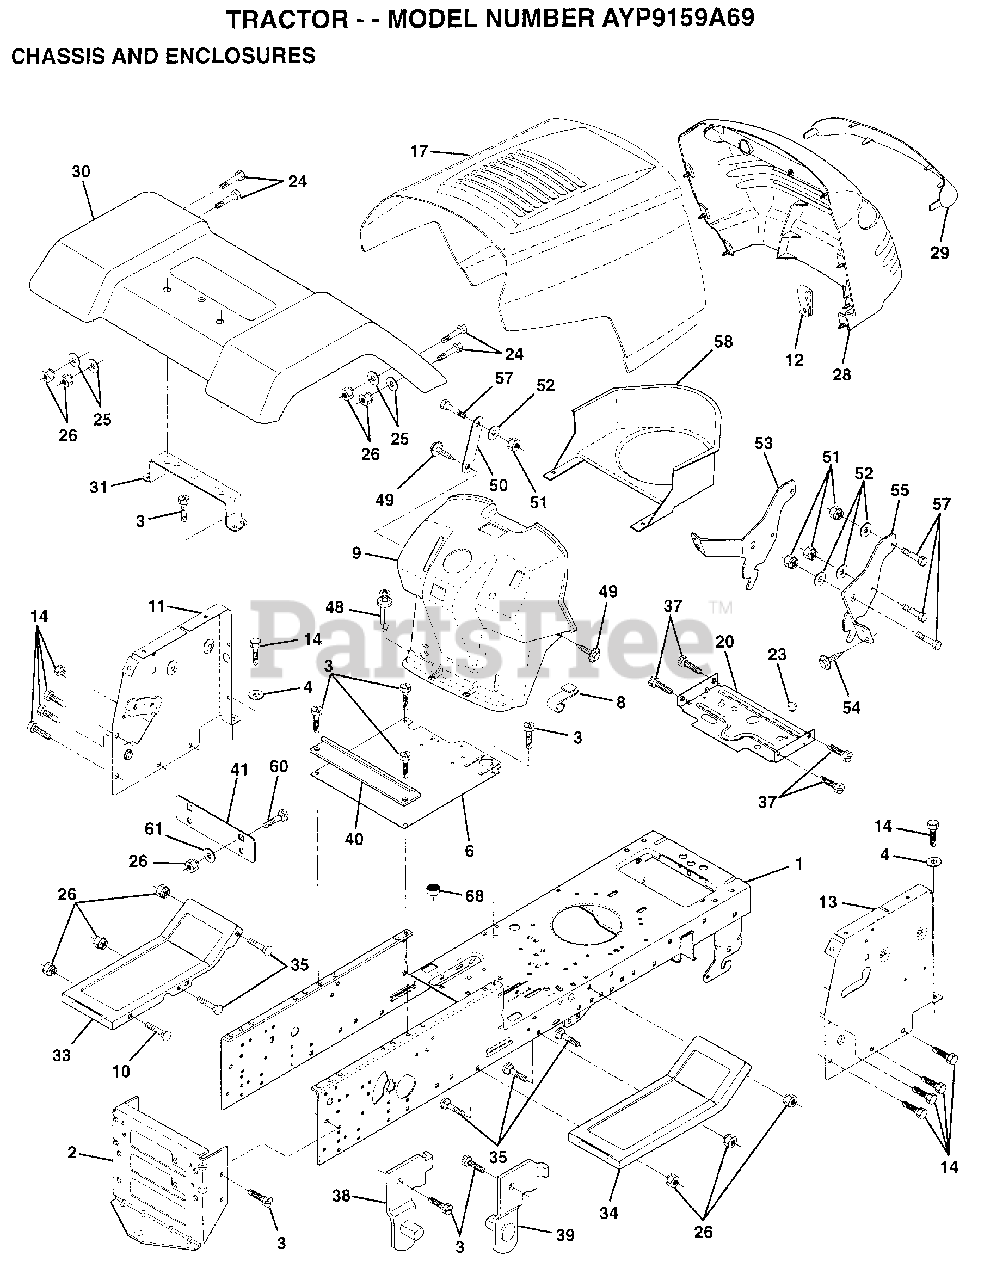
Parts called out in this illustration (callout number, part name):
1	CHASSIS.WLD.11GA
3	SCREW
4	WASHER
8	"CLIP,INSULATOR"
11	PANEL.DASH.LH.A
12	CLIP.TINNERMAN
13	PANEL.DASH.RH.
14	SCREW LT
17	HOOD.STL.PRV.LB
20	PLATE.MTG.BTRY.TK
24	BOLT
25	WASHER
26	NUT
28	GRILL.P/L.EURO.
29	LENS.EURO.W/DECAL
30	FENDER.PNT.LT.
31	BRACKET SUPT FEND
33	FOOTREST.LT.LT/GT
34	FOOTREST.RH.LT/GT
35	BOLT
37	SCREW LT
38	BRACKET ASM LH
39	BRACKET ASM RH
40	SPACER FENDER LT
41	PLATE EXTEN FEND
48	RIVET.PUSH.PLATE
49	SCREW HEX CRT
50	BRACE SUPT DASH
51	NUT
52	WASHER
53	BRACKET.GRILLE.LH
55	BRACKET.GRILLE.RH
58	AIR DUCT
60	BOLT
61	WASHER
68	NUT
